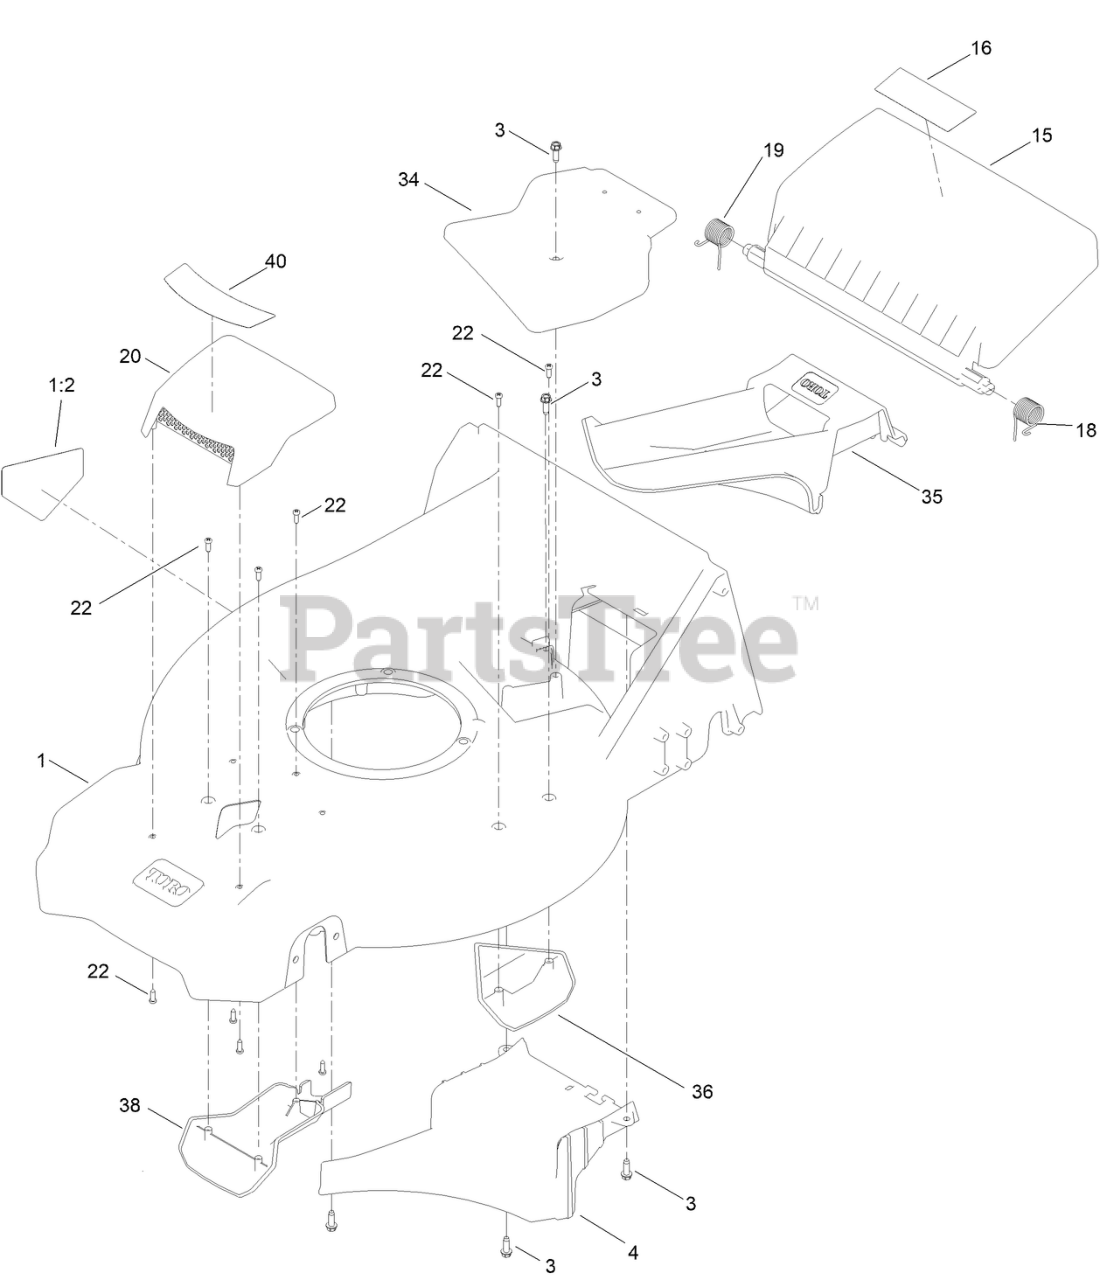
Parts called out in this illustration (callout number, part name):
1	HOUSING ASM
1:2	DECAL-DANGER
3	SCREW-HWHTF
4	RAMP-DISCHARGE
15	DOOR-REAR
16	DECAL-WARNING
18	SPRING-TORSION, LH
19	SPRING-TORSION, RH
20	ASM-COVER, TOP INTAKE
22	SCREW-PLASTIC, PPH
34	COVER-BELT, TOP
35	PLUG-MULCH
36	KICKER-HOUSING
38	COVER-INTAKE, BOTTOM
40	DECAL-COVER, INTAKE
